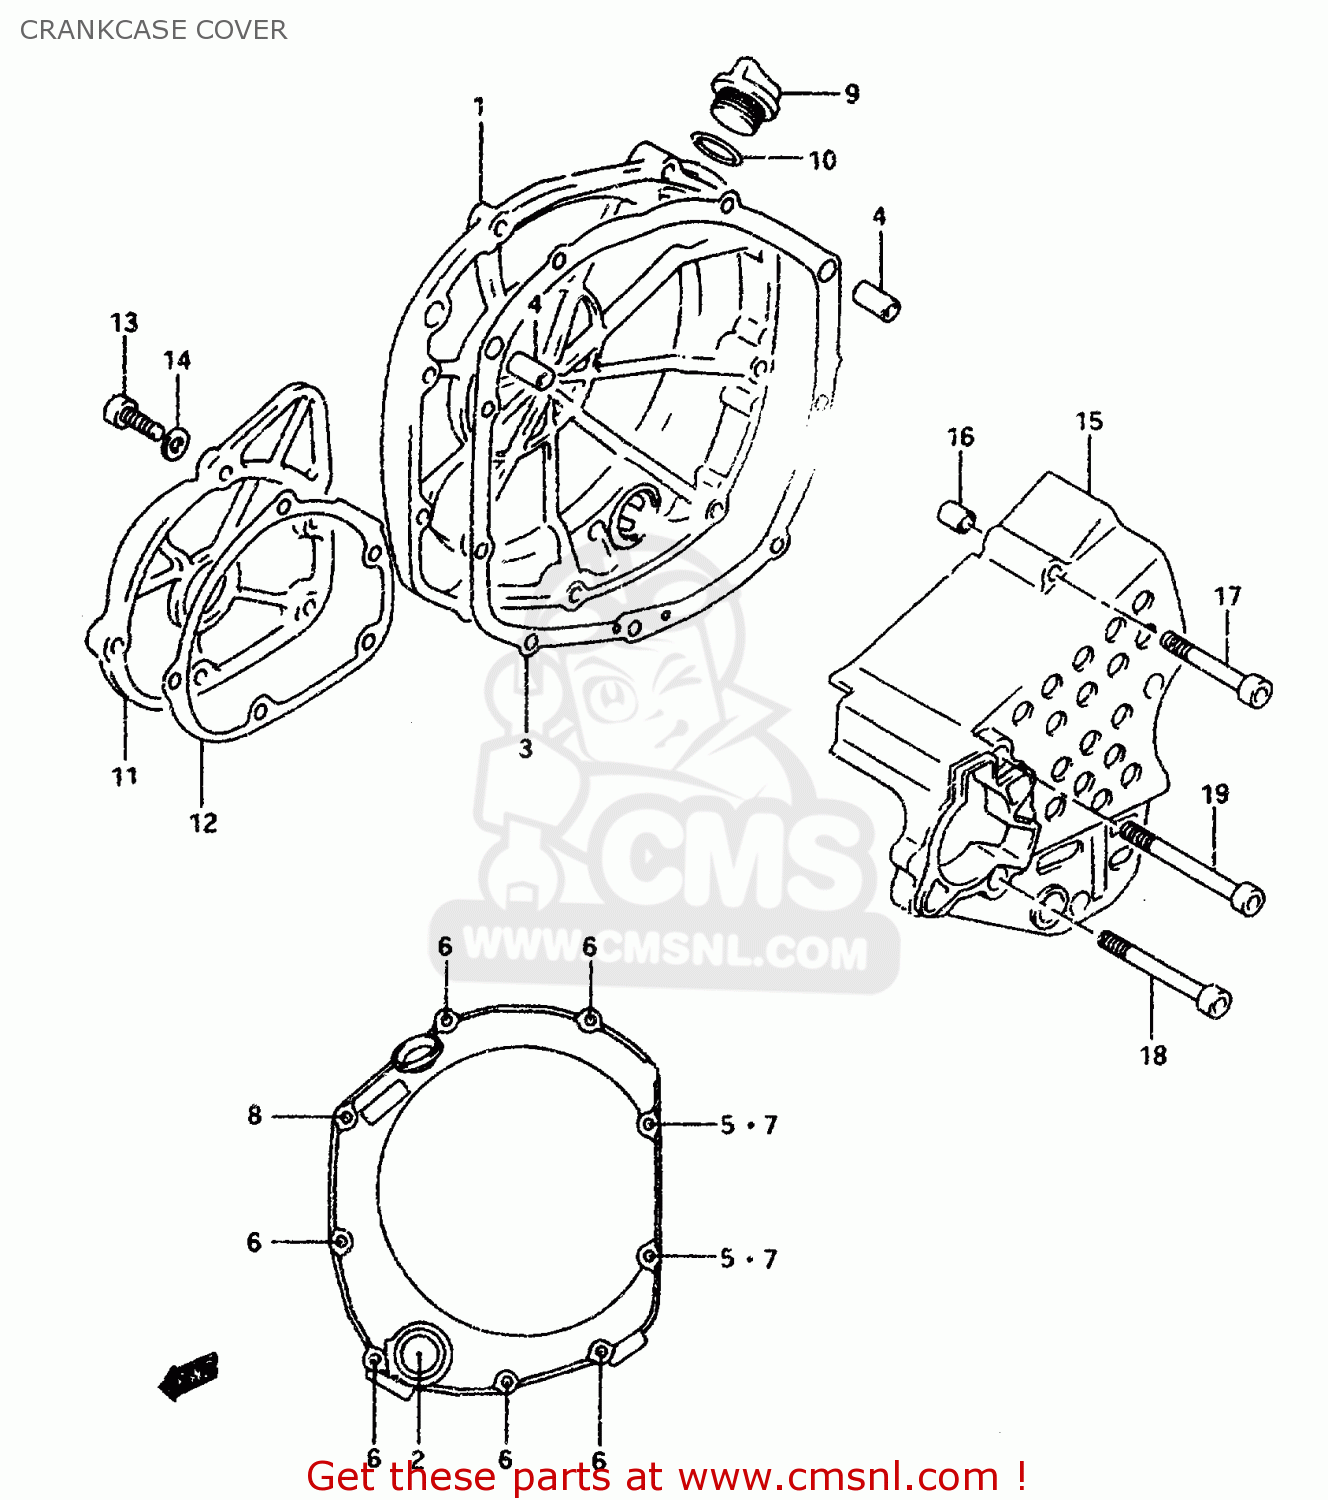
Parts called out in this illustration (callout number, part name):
1	COVER,CLUTCH
2	LENS,OIL LEVEL CHECK
3	GASKET,CL COVER (NAS)
4	PIN
5	GASKET(5.8X11X1.2) (NAS)
6	BOLT
7	BOLT
8	BOLT
9	PLUG
10	O RING(D:3.1,ID:16.8)
11	CAP
12	GASKET,SIGNAL GEN COVER
13	BOLT
14	GASKET(5.8X11X1.2) (NAS)
15	COVER,ENGINE SPROCKET
16	PIN
17	BOLT
18	BOLT
19	BOLT
